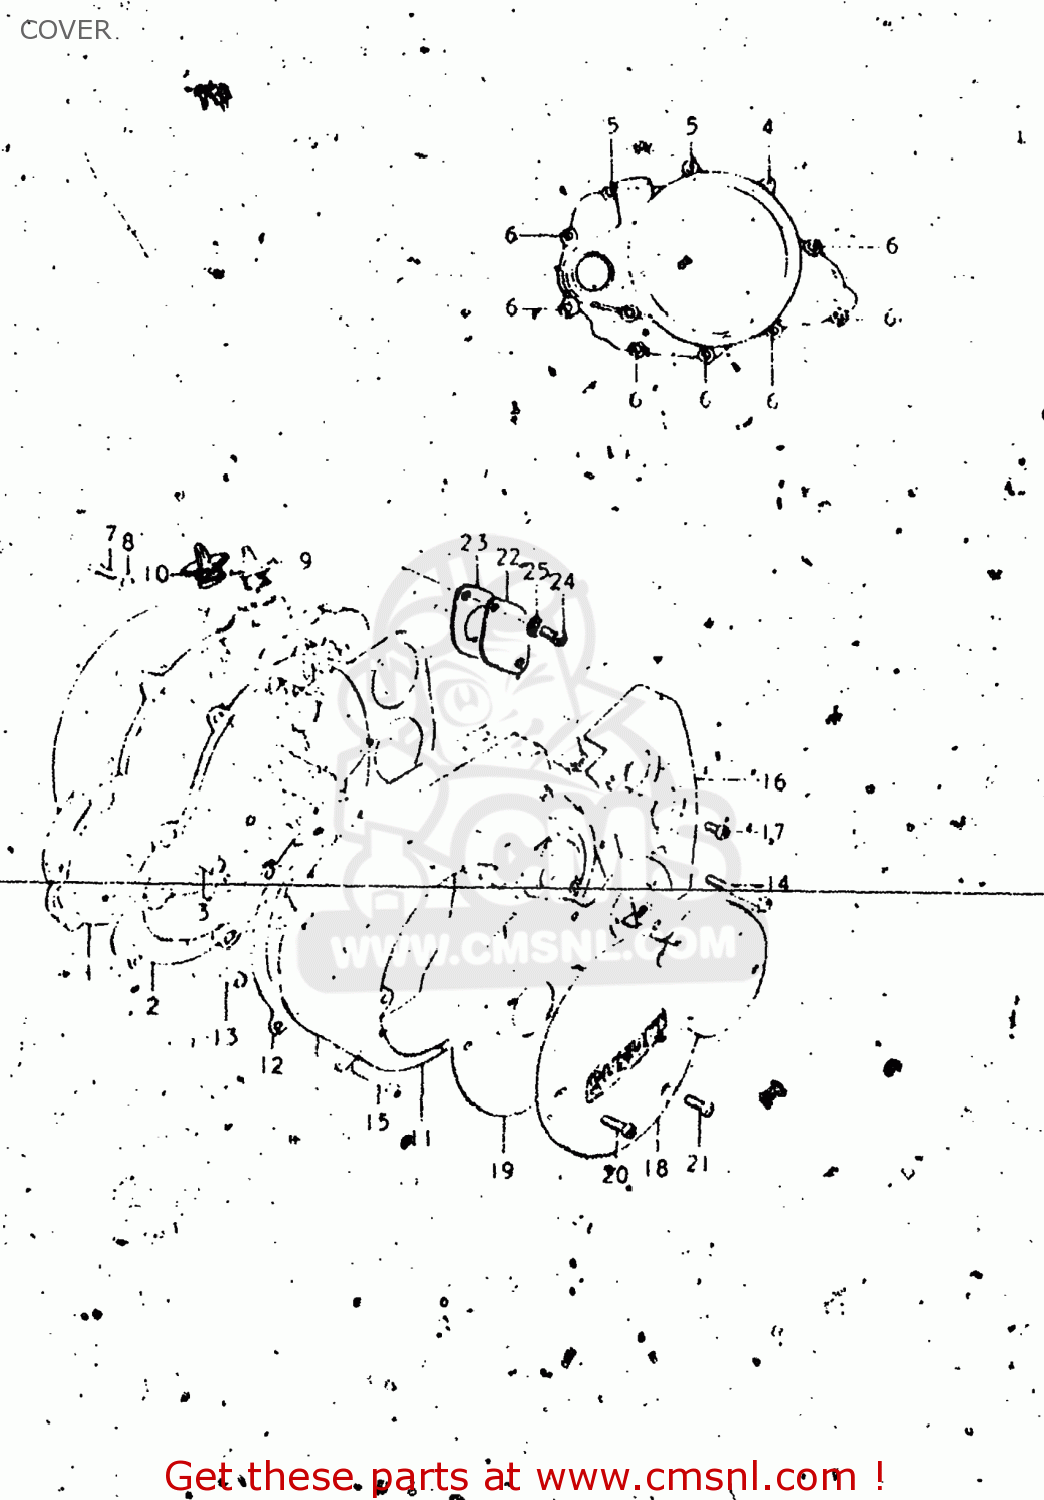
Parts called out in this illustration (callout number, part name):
1	COVER,CLUTCH
2	GASKET,CLUTCH COVER (MCA)
3	PIN
4	SCREW
5	SCREW (6X35)
6	SCREW
7	SCREW(6X10)
8	GASKET(6.2X11X1) (NAS)
9	PLUG,OIL FILTER
10	PLUG
11	COVER,MAGNETO
12	GASKET,MAGNETO COVER (NAS)
13	PIN
14	SCREW
15	SCREW
16	COVER,SPROCKET
17	SCREW
18	CAP,MAGNETO INSPECTION
19	GASKET,MAGNETO INSPECTION (NAS)
20	SCREW
21	SCREW
22	CAP,OIL PUMP DRIVE SHAFT
23	GASKET,OIL PUMP (MCA)
24	Screw
25	LOCK WASHER
